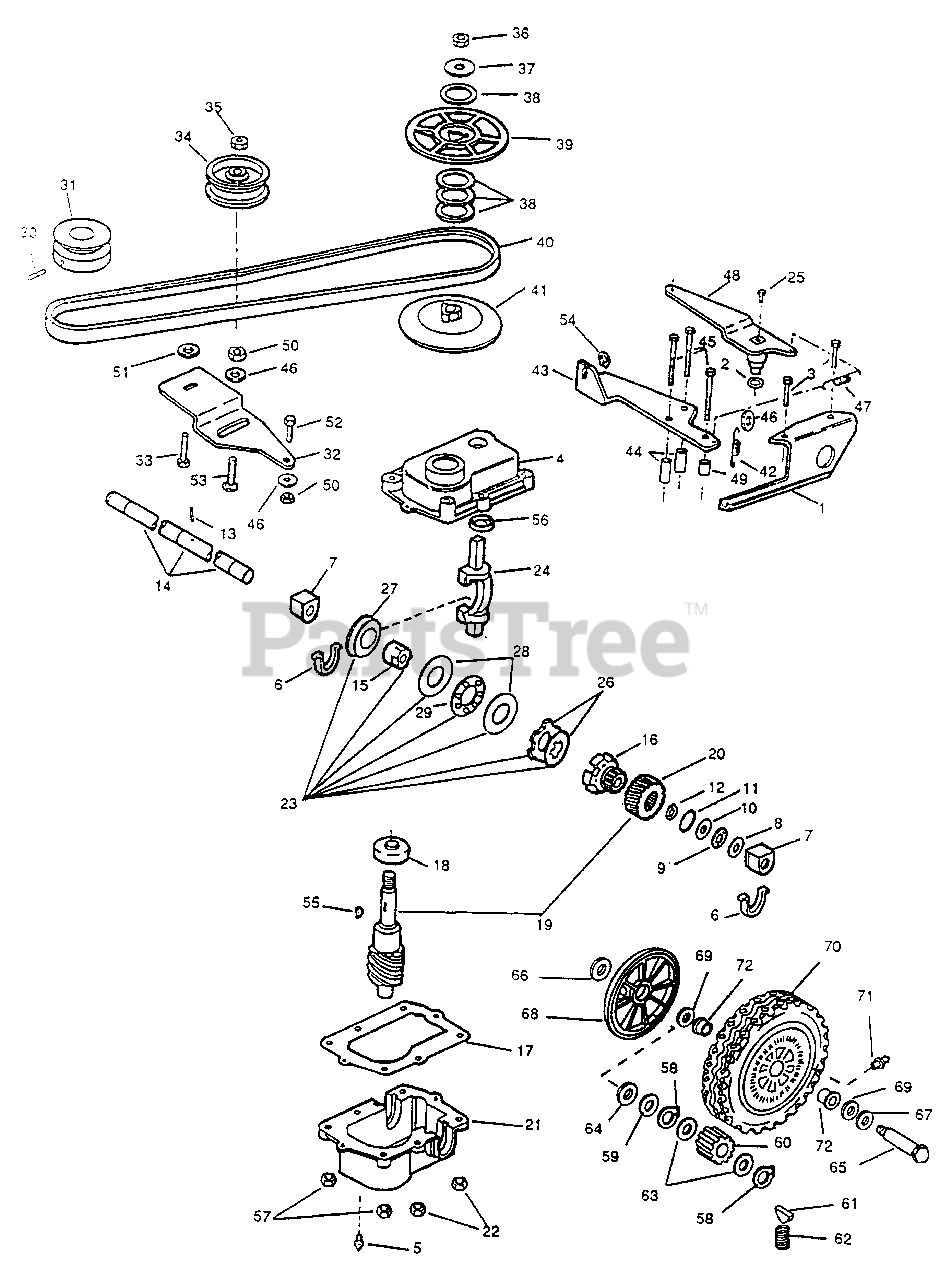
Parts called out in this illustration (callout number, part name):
1	Tensioner Bracket
2	O-Ring
3	Hex Hd. Cap Screw
4	Gearcase-Upper
5	Plug
6	Packing
7	Bearing & Seal-Gearcase
8	Thrust Washer
9	Thrust Bearing
10	Thrust Washer
11	Thrust Washer
12	Retaining Ring
13	Pin
14	Driveshaft
15	Driven Sleeve
16	Driver
17	Gasket
18	Bearing
19	Worm Wheel & Shaft (Inc. 20)
20	Worm Wheel
21	Gearcase-Lower
22	Nut, Lock
23	Collar, Brg & Disc Kit (Inc. 24-29)
24	Shift Fork
25	Screw
26	Disc Plate Kit
27	Collar
28	Thrust Washer
29	Bearing
30	Set Screw
31	Pulley-Engine
32	Bracket & Idler Assy (Inc. 33-35)
33	Screw
34	Pulley-Idler
35	Nut
36	Nut
37	Washer
38	Washer
39	Pulley-Upper Half
40	V-Belt
41	Pulley-Lower Half
42	Extension Spring
43	Conduit Anchor Bracket
44	Spacer
45	Screw
46	Washer
47	Extension Spring
48	Shift Arm & Hub Assembly
49	Spacer
50	Nut
51	Washer
52	Screw
53	Square Neck Bolt
54	Retaining Ring
55	Key
56	Seal Guide
57	Nut-Lock
58	Retaining Ring
59	Washer
60	Pinion
61	key
62	Spring
63	Spacer
64	Washer-Shim
65	Wheel Bolt
66	Felt Washer
67	Washer
68	Wheel Cover
69	Felt Washer
70	Wheel Assay (Inc. 71-72)
71	Lube Fitting
72	Bushing
